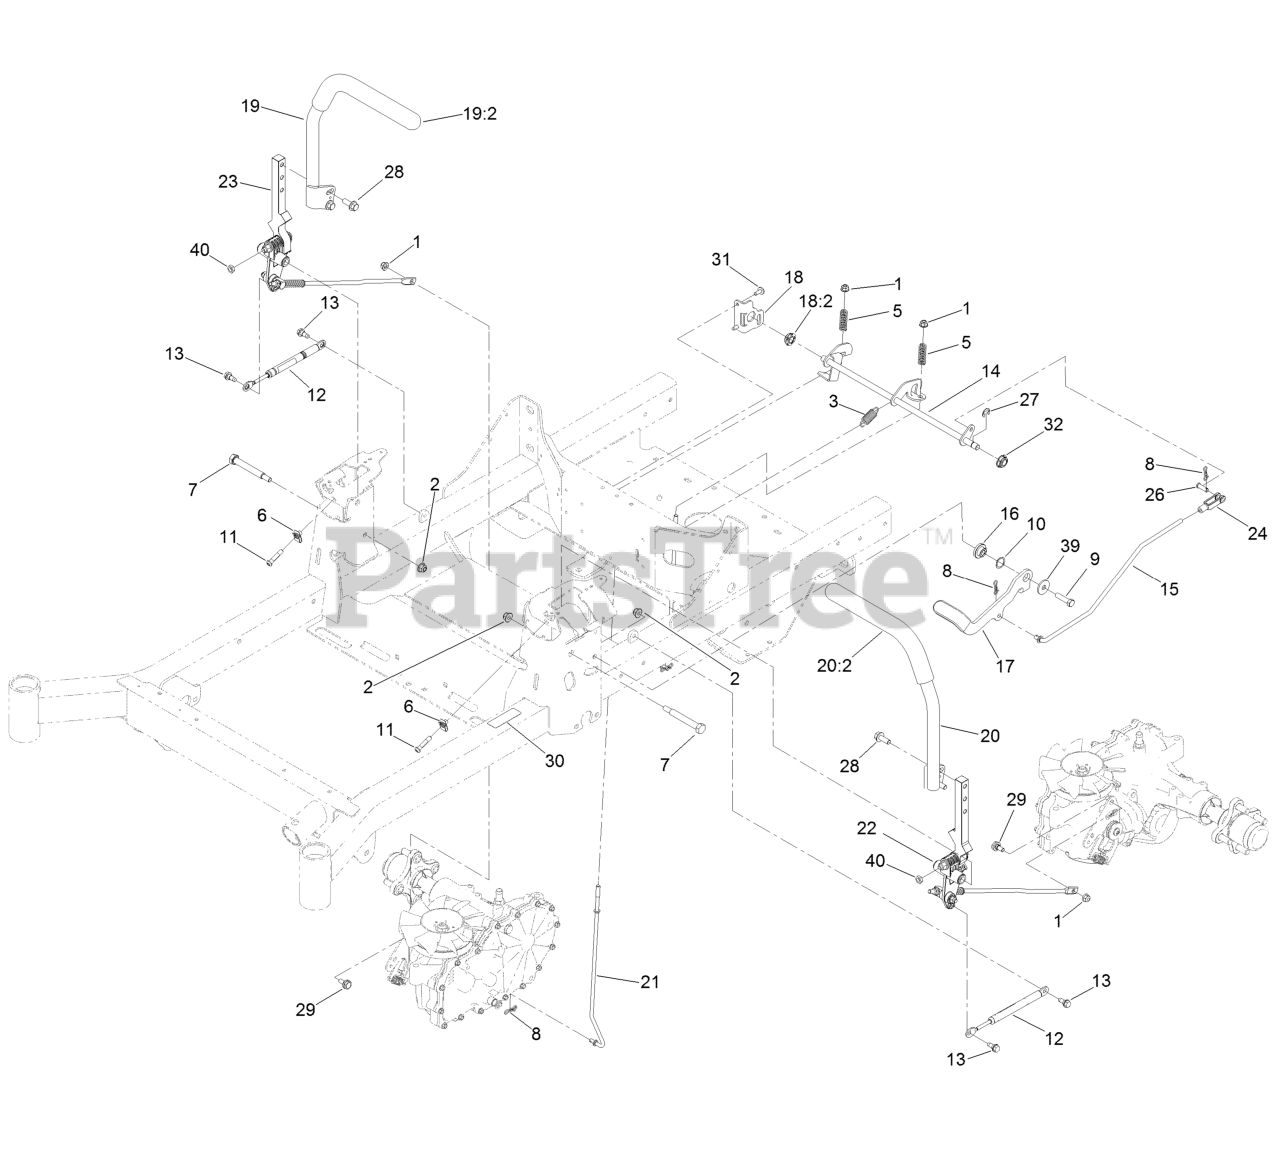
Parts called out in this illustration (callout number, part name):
1	Nut-HF, NI
2	Nut-HF, NI
3	Spring-Extension
5	Spring-Compression
7	Bolt-Pivot
8	Pin-Cotter, Locking
9	Screw-HH
10	Washer-Wave
11	Screw-HSBH
13	Screw-Shoulder
14	Shaft-Brake
15	Linkage-Brake, Upper
16	Pivot-Flange
17	Lever-Brake (With Grip)
18	Bracket-Brake
18:2	Bearing-Spherical
19	RH Control Handle ASM
20	LH Control Handle ASM
21	Linkage-Brake, Lower
22	LH Motion Control ASM
23	RH Motion Control ASM
24	Yoke-Adjustable
26	Pin-Clevis
27	Ring-Retaining, External
28	Screw-HHF
29	Bolt-Shoulder
30	Decal-Brake, Parking
31	Screw-Torx
32	Bearing-Spherical
39	Washer
40	Nut-Jam
